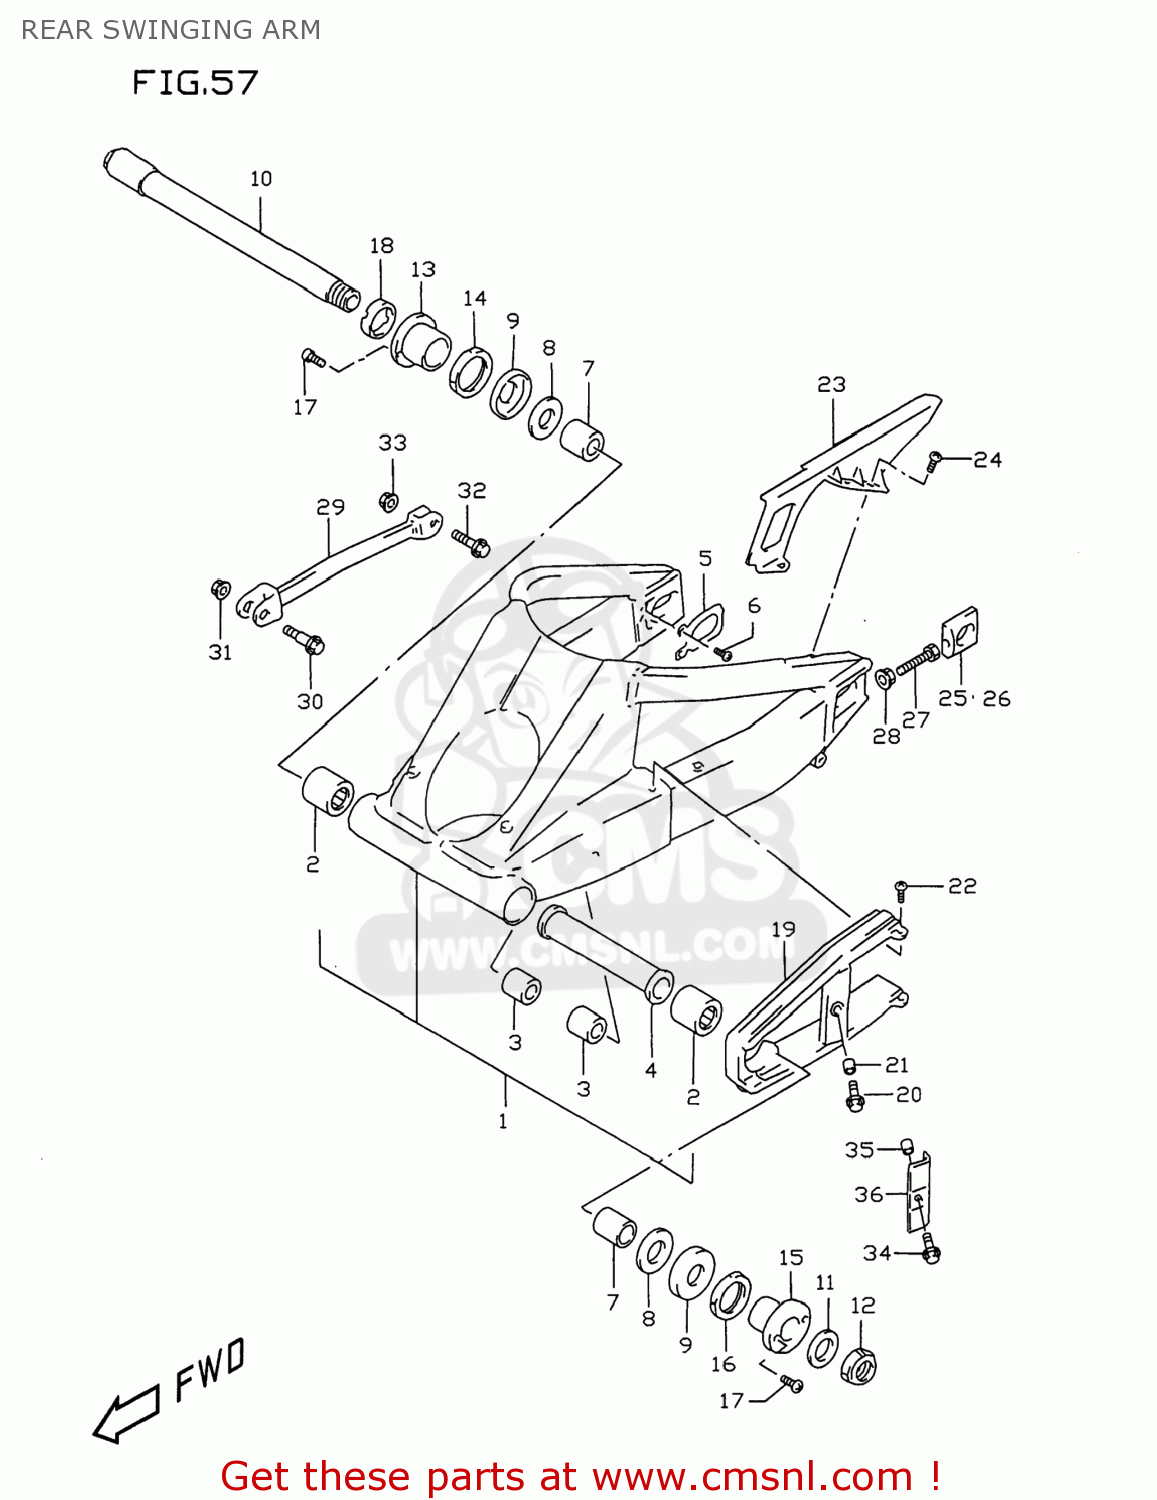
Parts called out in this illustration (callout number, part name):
1	SWINGINGARM ASSY,RR
2	BEARING(30X40X25)
3	BEARING(17X24X20)
4	SPACER COMP,REAR SWING PIVOT
5	PLATE,RR SWING ARM BRKT
6	SCREW 6X10
7	SPACER,REAR SWING ARM PIVOT
8	WASHER
9	DUST SEAL,RR SWGARM PIVOT
10	SHAFT,RR SWINGINGARM PIVOT
11	WASHER(25.2X42X3.2)
12	NUT
13	BOSS,RR SWINGINGARM PIVOT,R
14	NUT,RR SWGARM PIVOT BOSS,R
15	BOSS,RR SWINGINGARM PIVOT,L
16	NUT,RR SWGARM PIVOT BOSS,L
17	SCREW
18	NUT,REAR SWING ARM PIVOT
19	BUFFER,CHAIN TOUCH DEFENSE
20	BOLT 6X20,WITH PLAIN WASHER
21	SPACER(6.5X10X8)
22	SCREW
23	CASE,CHAIN
24	SCREW(6X16)
25	ADJUSTER,CHAIN,R
26	ADJUSTER,CHAIN,L
27	BOLT(8X50)
28	NUT
29	TORQUELINK,RR
30	BOLT
31	NUT
32	BOLT(10X37)
33	NUT
34	BOLT
35	SPACER(6.5X10X10)
36	PLATE,CHAIN BUFFER
